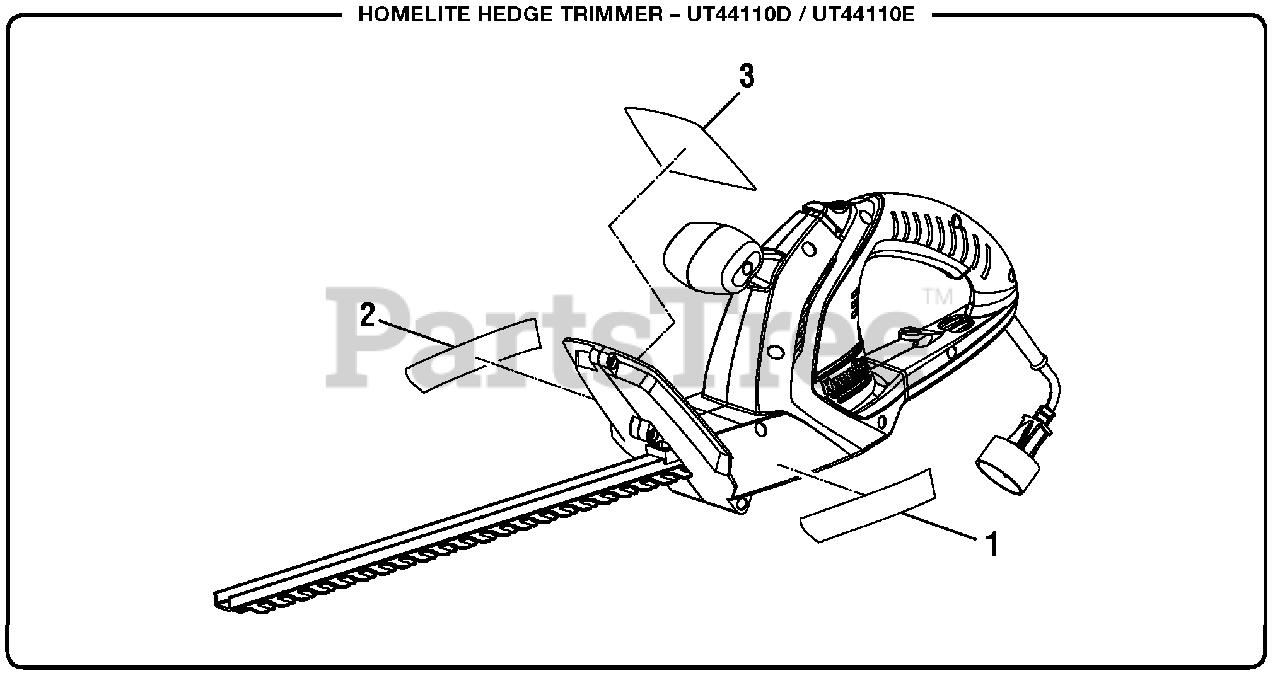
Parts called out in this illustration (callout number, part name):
1	Homelite Logo Label (Left)
2	Homelite Logo Label (Right)
3	Data Label (UT44110E)
3	Data Label (UT44110D)
